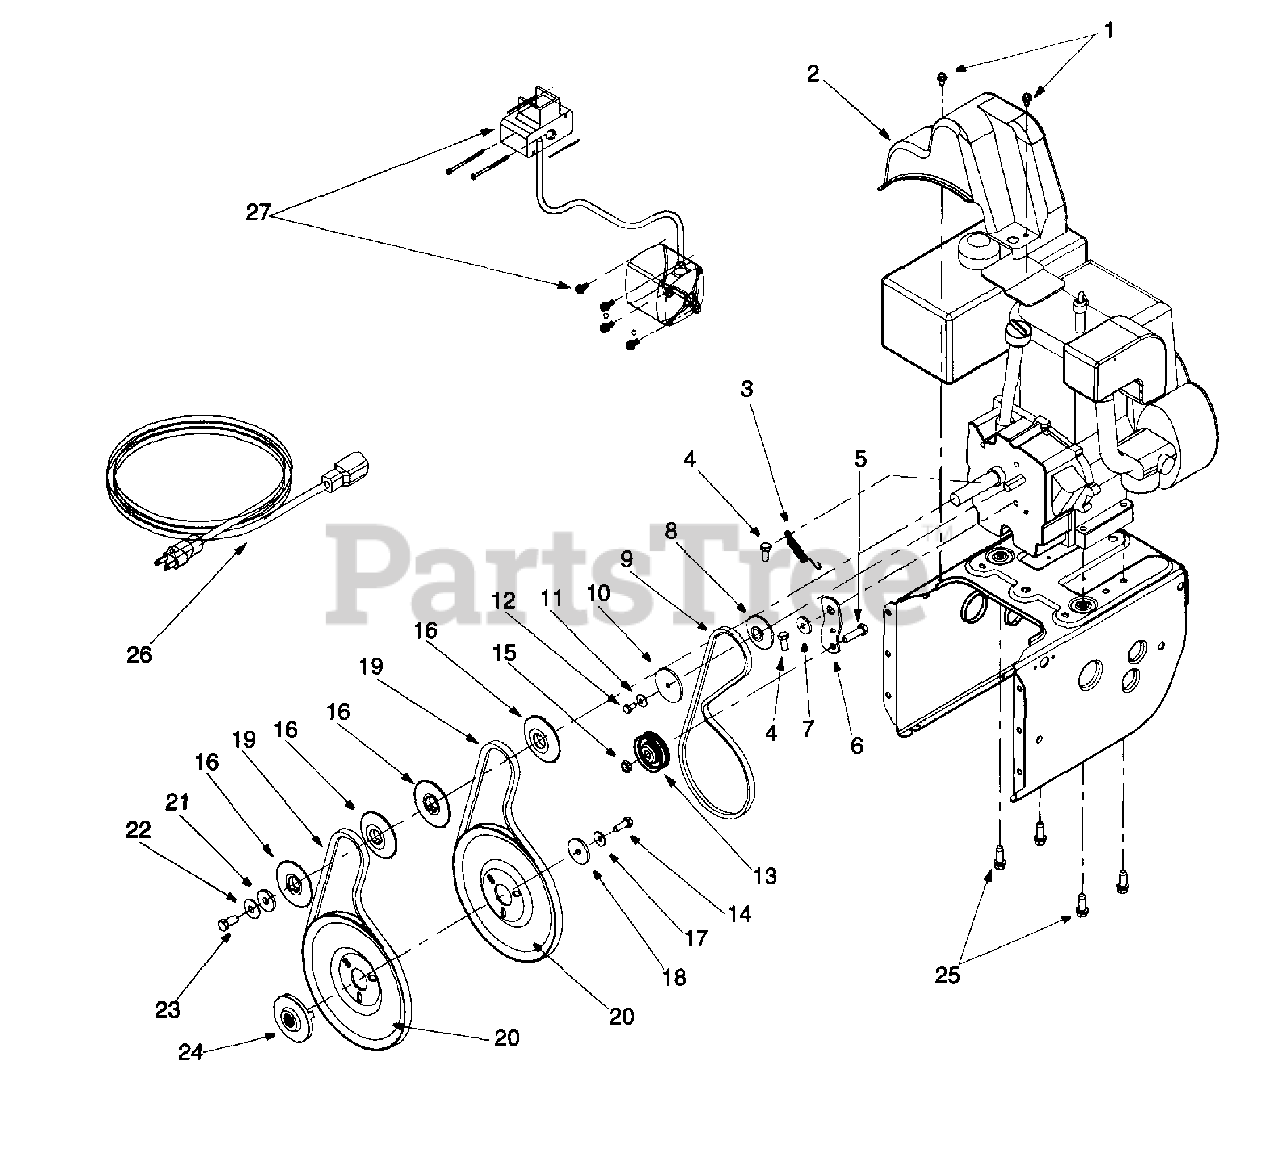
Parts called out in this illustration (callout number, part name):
1	Hex Washer Screw 1/4-20 x .50
2	Belt Cover
3	Extension Spring
4	Hex Screw 5/16-24 x .75
5	Hex Cap Screw 3/8-16 x 1.25
8	Pulley Half
9	V-Belt
10	Pulley Half
11	Bell Washer
12	Hex Cap Screw 1/4-28 x .50
13	Flat Idler
14	Lock Hex Cap Screw 5/16-24
15	Lock Jam Nut 3/8-16
16	Pulley Half
17	Bell Washer
18	Flat Washer
19	Belt
20	Auger Pulley
21	Flat Washer 3/8 x 1.25 OD
22	Bell Washer
23	Hex Cap Screw.3/8-24
24	Adapter Pulley
25	Hex Screw 3/8-16 x 1.0
26	Extension Cord
27	Electric Start
